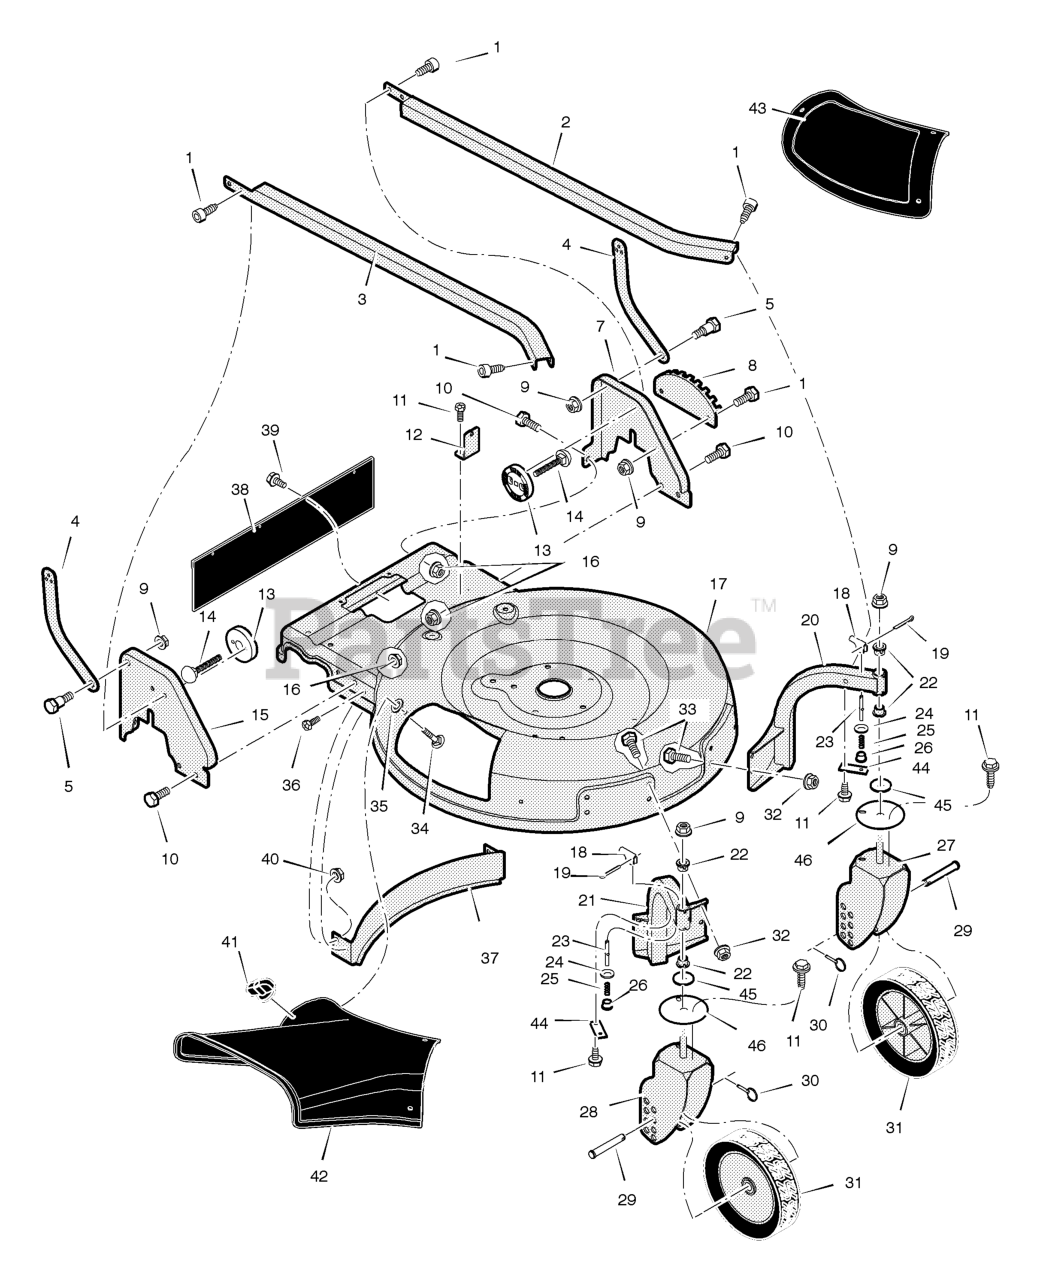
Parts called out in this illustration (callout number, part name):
2	Brace, Left
3	Brace, Right
4	Support, Handle
5	Bolt, Shoulder
7	Bracket, Left Handle
8	Plate, Index
9	Nut, Flange
10	Screw
12	Bracket, Blade Drive Cable
13	Support, Handle Adjuster
14	Bolt, Carriage
15	Bracket, Right Handle
17	Housing, Mower
18	Lever, Wheel Lock
19	Pin, Cotter
20	Bracket Assembly, Left Caster
21	Bracket Assembly, Right Caster
23	Rod, Wheel Lock
25	Spring, Compression
27	Bracket Assembly, Left Wheel
28	Bracket Assembly, Right Wheel
29	Axle, Caster
30	Pin, Cotterless Hitch
31	Wheel and Tire
32	Nut, Flange
33	Bolt, Hex
34	Bolt, Carriage
35	Retainer, Bolt
37	Baffle, Rear
38	Deflector, Rear
42	Deflector, Chute
43	Cover, Mulch
44	Plate, Locking Arm
45	Washer
46	Plate, Locking
